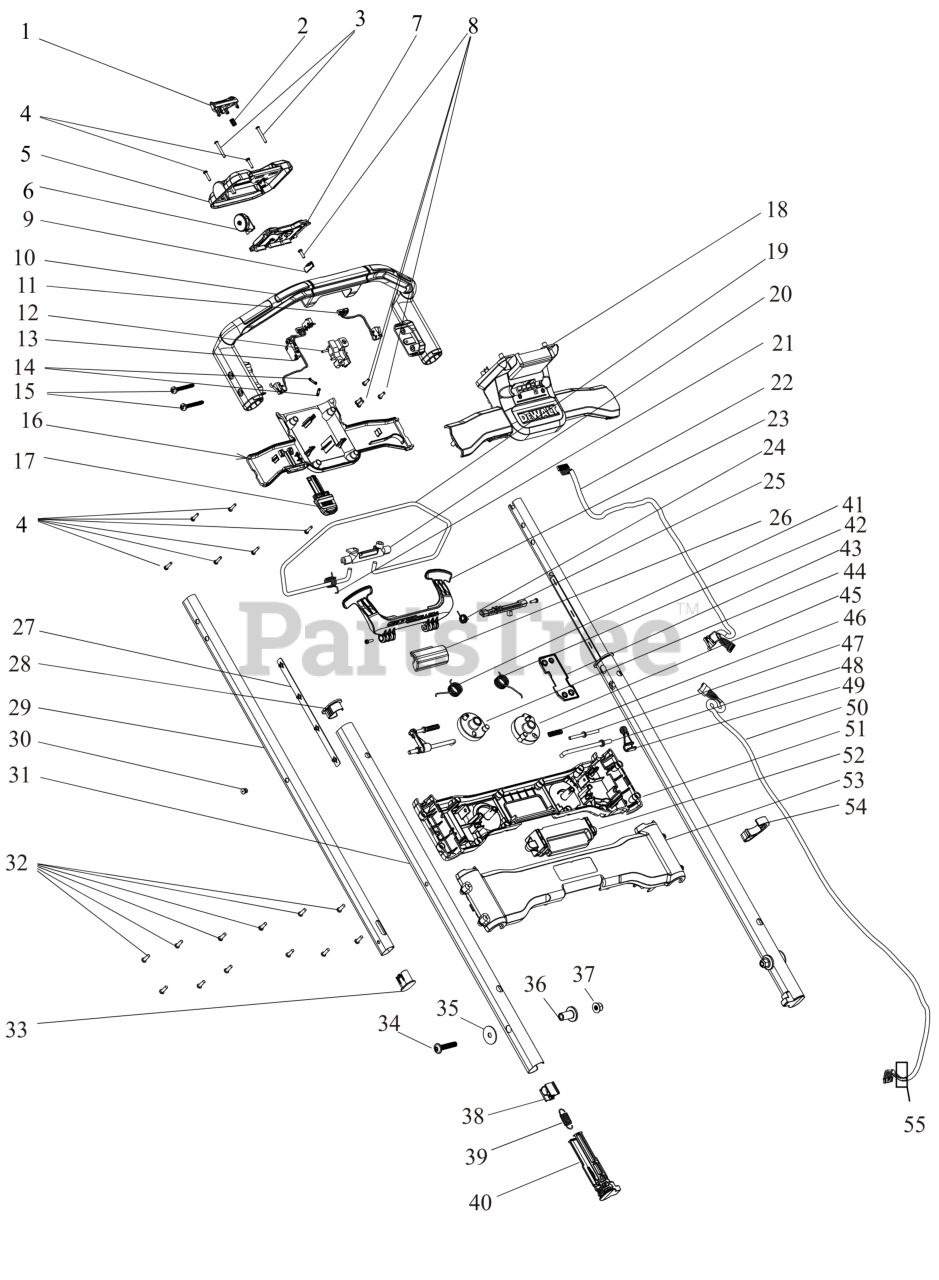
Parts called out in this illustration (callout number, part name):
1	BUTTON
2	SPRING
3	SCREW
5	COVER
6	POTENTIOMETER SA
7	CONTROL
9	BUTTOM
10	HANDLE
11	WIRE HARNESS
12	SWITCH
13	WIRE HARNESS
15	SCREW M6X45-T30-THD FRM
16	SWITCHBOX
18	HOUSING SA
19	CATCH
21	SPRING TORSION
22	WIRE HARNESS
23	PADDLE
24	PADDLE
25	PIVOT
26	COVER
27	STRIP
28	SLEEVE
29	TUBE UPPER
31	TUBE LOWER
32	SCREW M4.55X16 T20-PLAS THD FRM
33	SLEEVE
35	WASHER
36	SCREW
39	SPRING
41	SPRING
42	SPRING
43	COVER
46	SPRING
49	HOLDER
50	HARNESS
51	COVER
52	BUTTON
53	COVER
55	CORE
56	GRASSBAG
57	FRAME
58	CHUTE
61	SPACER
62	SCREW 1/4-10 x .750
63	SUPPORT
64	BRACKET
65	LOCK-NUT
68	SPRING
69	BRACKET
70	SUPPORT
71	BRACKET
72	SHIELD
73	INSERT
74	FLANGE LOCK NUT
75	WHEELS
76	COVER LH
77	AXLE REAR
79	SPRING
82	BEARING
83	HOLDER
84	SCREW
85	TRANSMISSON SA
86	HARNESS
88	AXLE FRONT
90	WHEELS
91	PLATE
93	BLADE MOUNT
94	BLADE MOUNT
95	WASHER
97	PLATE
101	SPRING
102	MOTOR SA
103	MODULE
104	PCB SA
105	BAFFLE
106	CONNECTOR
107	HARNESS
108	WIRE HARNESS
109	COVER
110	PLATE SA
112	HOUSING SA
115	COVER SA
116	BUSHING
117	COVER
118	SA HANDLE PNL KIT RWD-YELLOW
119	LABEL
866	20V BATTERY MAX XR 10AH DCB210
871	CHARGER
